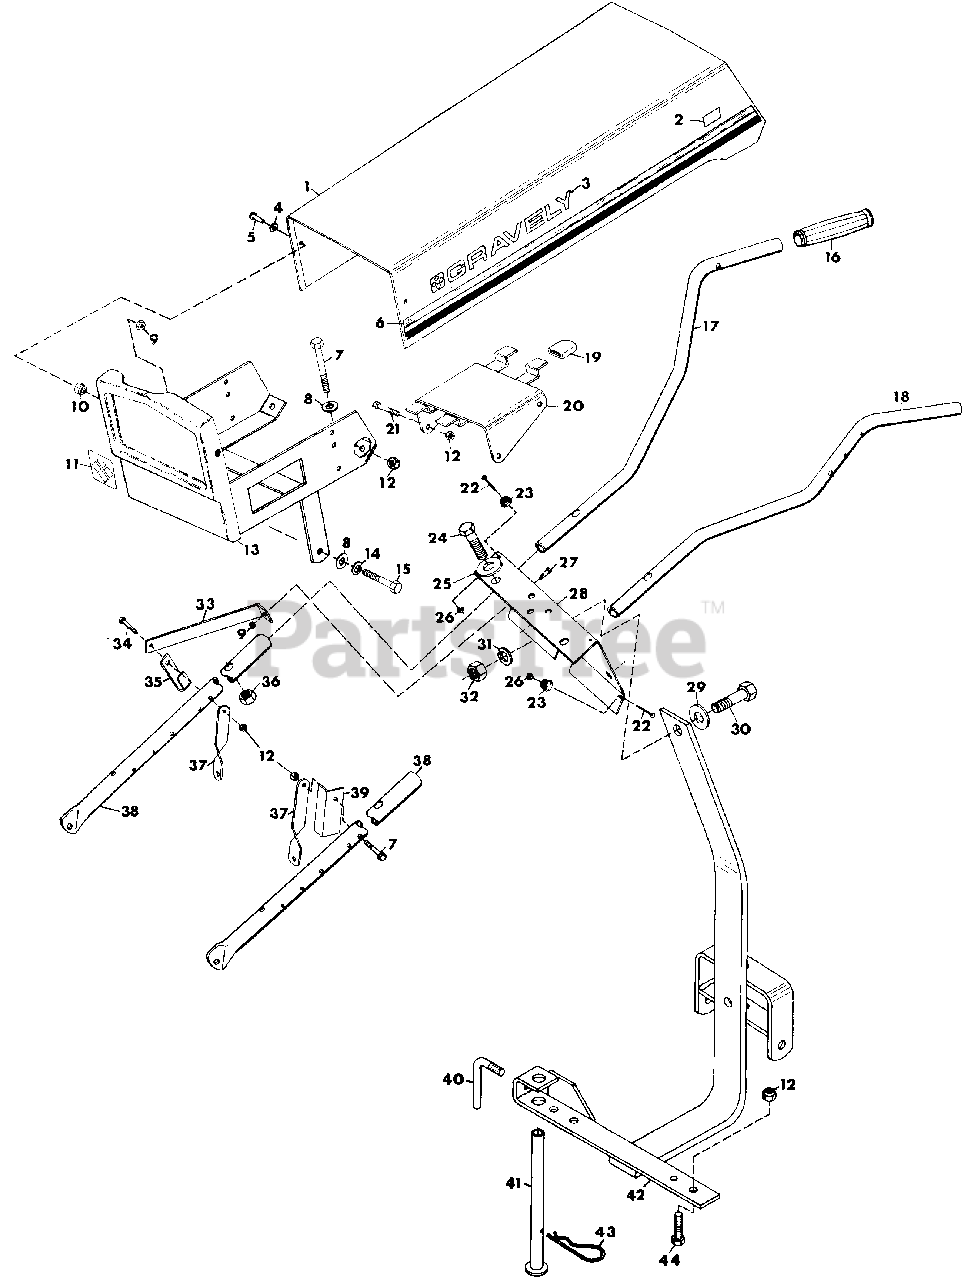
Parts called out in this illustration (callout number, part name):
1	HOOD
2	DECAL, MODEL 5665
2	DECAL, MODEL 5260
2	DECAL, MODEL 5645
2	DECAL, MODEL 5465
3	DECAL, GRAVELY LOGO
4	WASHER, FLAT .281X.625X.065
5	SCREW, MACH. 1/4-20X1 PAN HD
6	DECAL, SIDE STRIPES
7	BOLT, HEX 3/8-16X2.25
8	WASHER, FLAT .406X.812X.065
9	NUT, LOCK 1/4-20
10	PIVOT, HOOD
11	DECAL
12	NUT, LOCK 3/8-16
13	WELDMENT, BATTERY BRACKET
14	WASHER, LOCK 3/8 REG.
15	BOLT, HEX 3/8-16X1.25
16	GRIP, HAND
17	BAR, RIGHT HANDLE
18	BAR, LEFT HANDLE
19	COVER, 1.0X.125X1.0
20	WELDMENT, FUEL TANK BRACKET
21	BOLT, HEX 3/8-16X1.875
22	SCREW, MACH. 6-32X5/8 PAN HD CR
23	BUMPER
24	BOLT, HEX 1/2-20X2
25	WASHER, FLAT .531X1.062X.095
26	NUT, MACH. LOCK 6-32
27	BOLT, HEX 1/4-20X.625
28	INSTRUMENT PANEL MODEL 5260
28	INSTRUMENT PANEL MODEL 5645
28	INSTRUMENT PANEL MODEL 5665
29	WASHER, FLAT .656X1.250X.100
30	BOLT, HEX 5/8-11X1.50
31	WASHER, LOCK 5/8 SP
32	NUT, HEX 5/8-11
33	BRACE, INSTRUMENT PANEL
34	BOLT, HEX 3/8-16X2.50
35	RETAINER, 2-SPEED CONTROL
36	NUT, HEX 1/2-20
37	BRACE, HANDLE
38	TUBE, SUPPORT
39	STOP, ROD
40	HANDLE, ADJUSTING
41	KICK STAND
42	HITCH, WELDMENT 8 H.P.
42	HITCH, WELDMENT 10 H.P., 12 H.P., 16 H.P.
43	PIN, HAIR
44	BOLT, HEX 3/8-16X1.50
NS	DECAL, AMERICA
